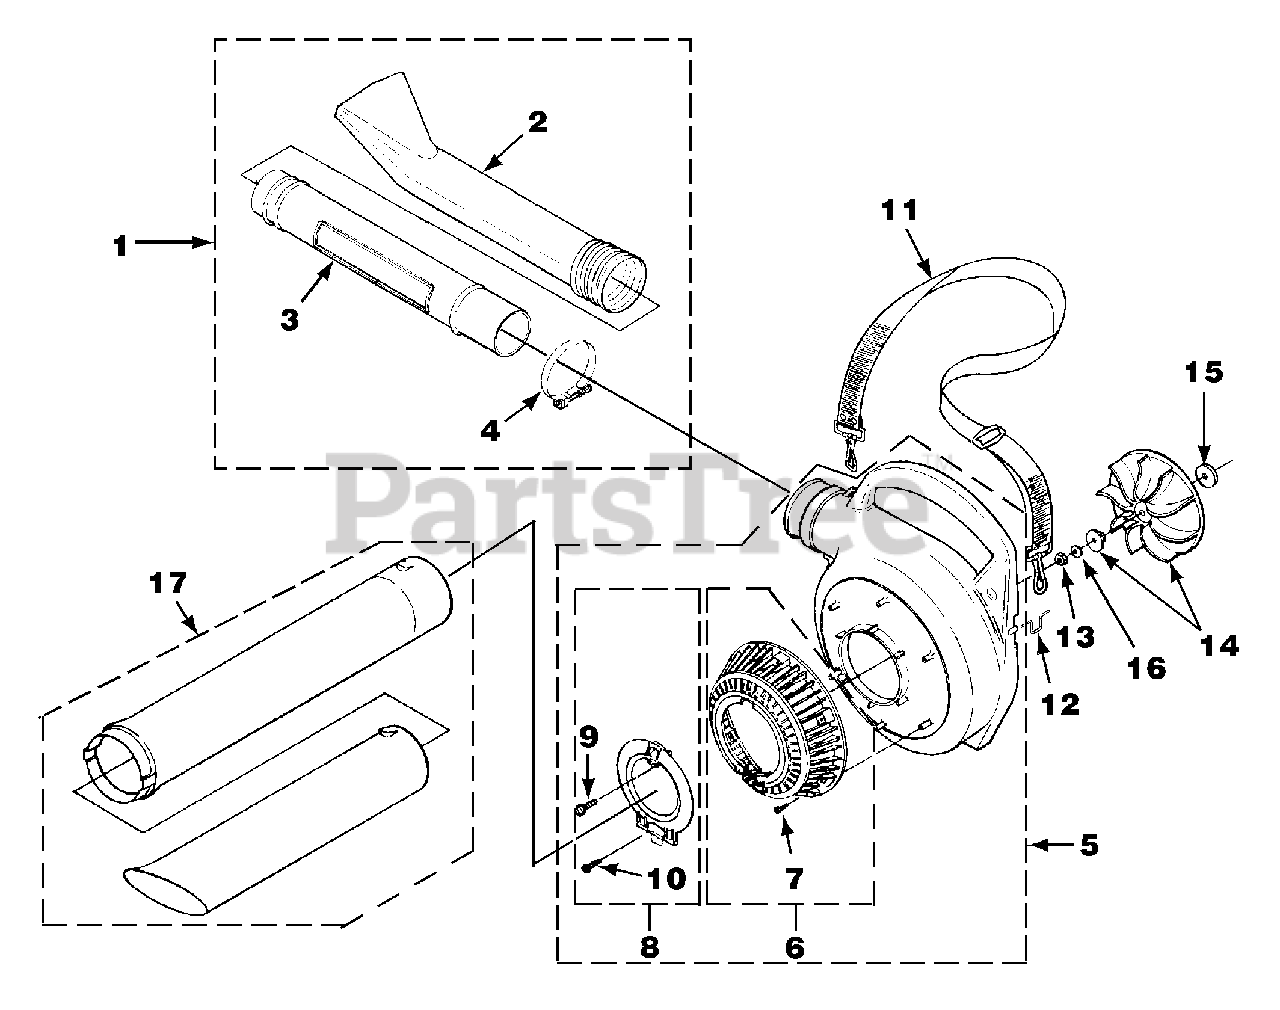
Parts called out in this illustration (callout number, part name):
1	BLOWER TUBE KIT
2	NOZZLE-Sweeper
3	TUBE
4	CLAMP w/Fasteners
5	VOLUTE HOUSING KIT
6	BLOWER VAC GRILLE KIT
7	SCREW-Thread Form. (#6 X 3/8")
8	ACCESS DOOR KIT
9	SCREW-Thread Rolling (#10 X 5/8")
10	SCREW-Thread Form. (#8 X 1/2")
11	SHOULDER STRAP
12	WIRE LOOP
13	NUT-Hex (3/8-24)
14	BLOWER FAN KIT
15	WASHER-Flat
16	WASHER-Bellville (3/8")
17	TUBE Kit w/Decals
